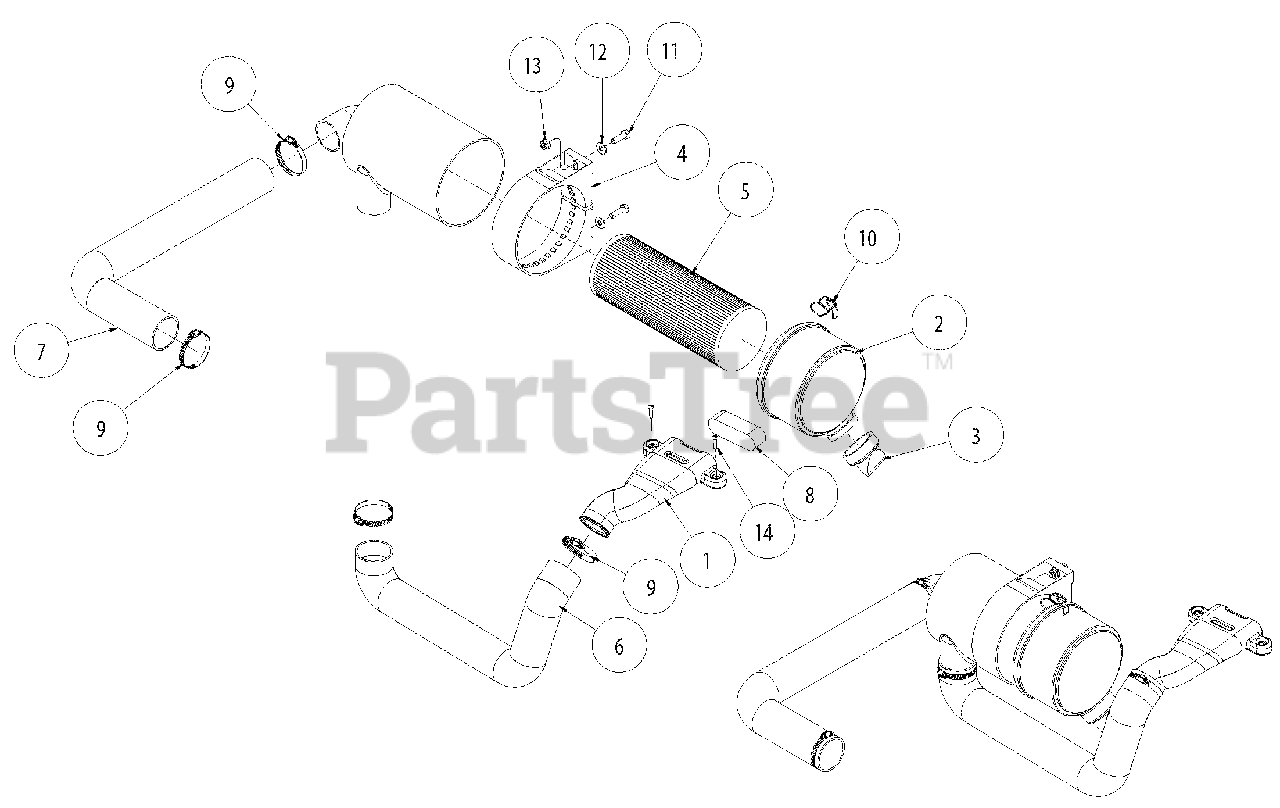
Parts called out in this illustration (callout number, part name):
1	SNORKEL AIR INTAKE
2	DNLDSN COVER W/LATCHES P533761
3	DNLDSN VACUATOR (BURP) P522958
4	DNLDSN AIR CLNR CLAMP PPGF30
5	FILTER AIR OUTER ELEMENT
6	SNORKEL TUBE
7	INTAKE TUBE
8	FILTER, AIR INTAKE
9	CLAMP WRM DRV#36SS (1.81-2.75)
10	DNLDSN LATCH P538928
11	HHCS 5/16-18 X 1 GR5 ZNYCR
12	WASHER FLAT 5/16 HARD ASTMF436
13	NUT HEX FLG TP LK 5/16-18ZNYCR
14	SCR SELF TAP #10 X 3/4
